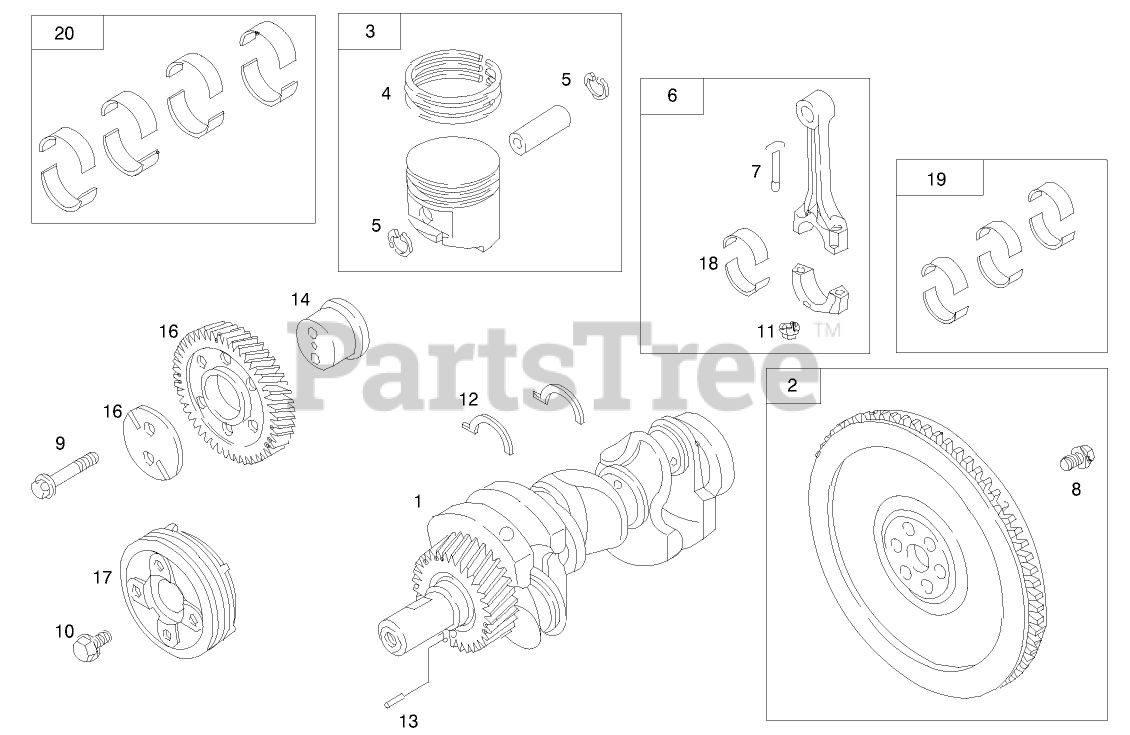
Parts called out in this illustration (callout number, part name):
3	PISTON ASM
4	RING SET
5	LOCK-PIN, PISTON
6	SEE PARTS BULLETIN #949
7	SCREW
8	SCREW-HEX
9	SCREW-HEX
10	SCREW-HEX
11	NUT-HEX
12	SHIM-ENDPLAY
13	PIN-LOCATING
14	GEAR-DRIVE
15	SHAFT-GEAR
16	PLATE-GEAR, IDLER
20	MAIN BEARING SET (SET OF 8)
